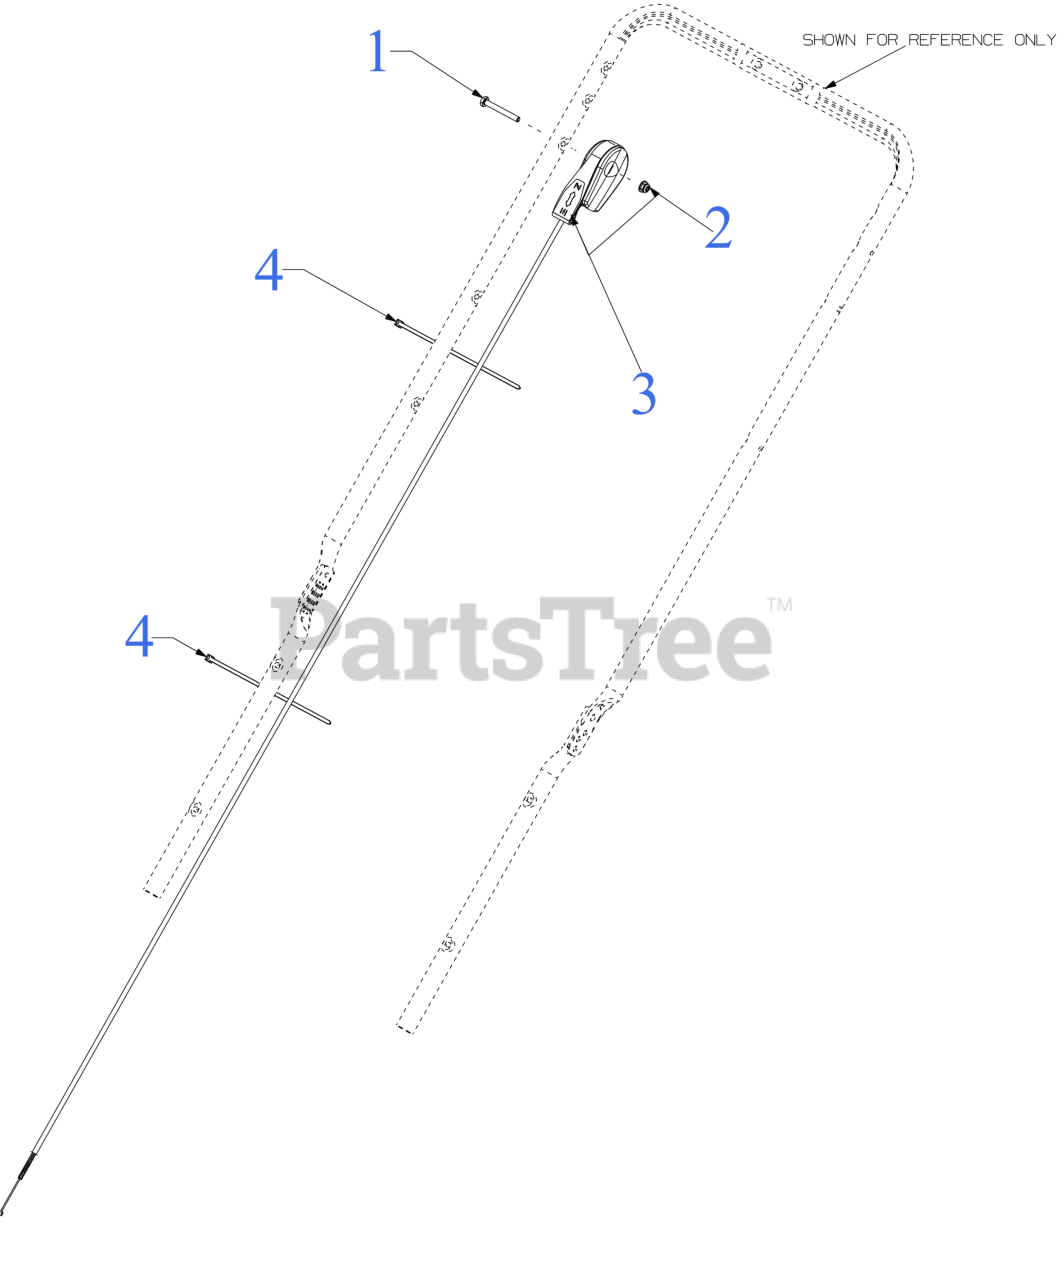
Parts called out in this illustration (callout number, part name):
1	SCREW 1/4-20 x 2 GR5
2	FLANGE LOCK NUT
3	CHOKE CABLE
4	7" CABLE TIE
